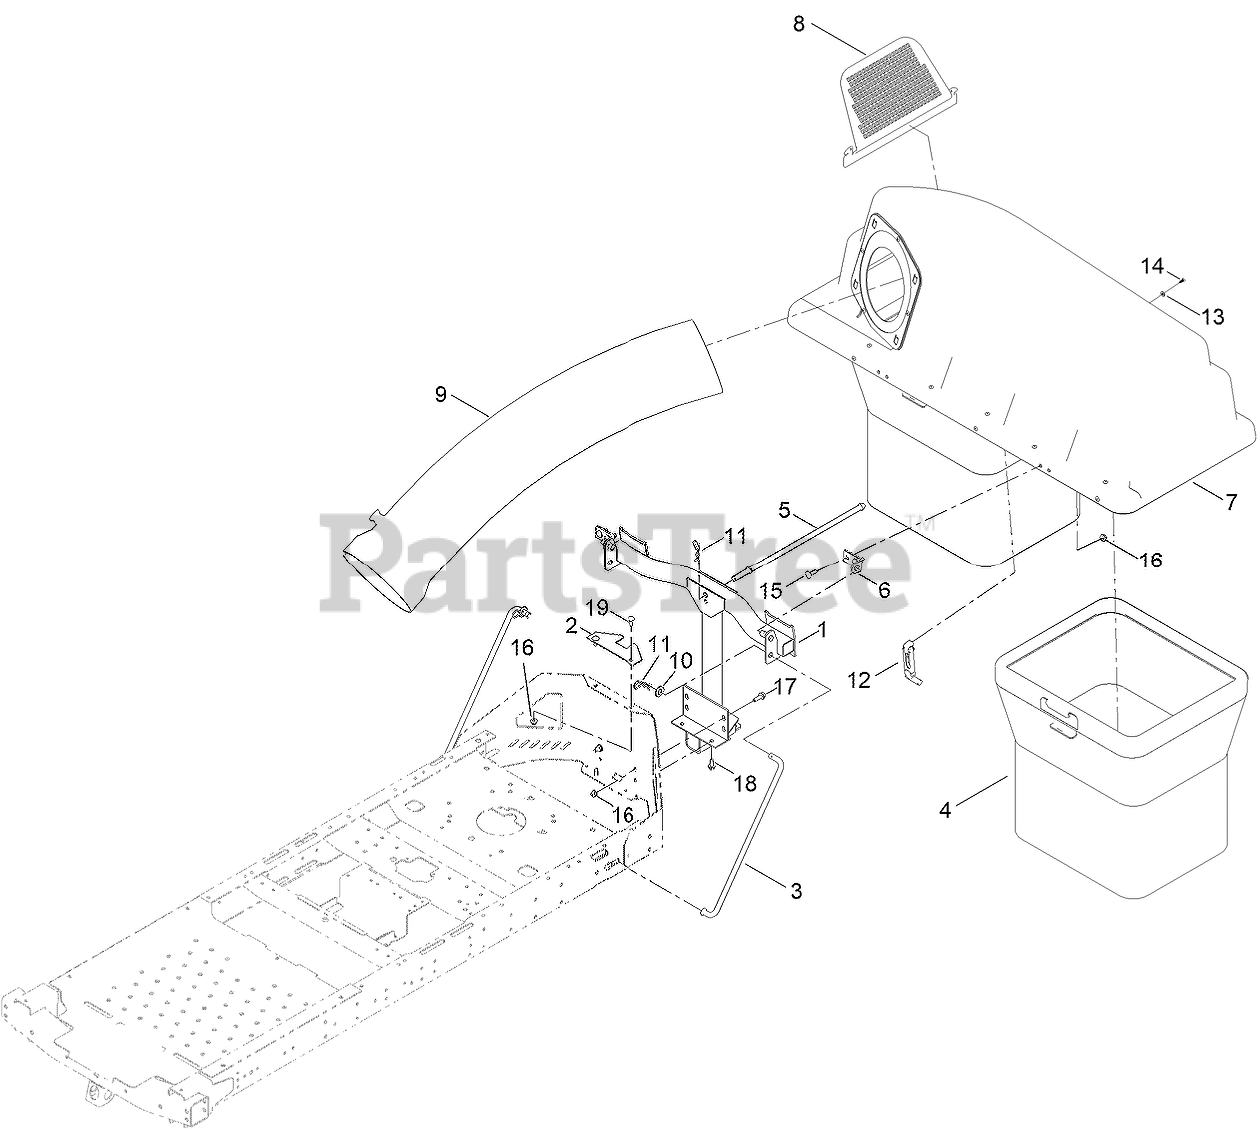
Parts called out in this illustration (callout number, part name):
1	Frame ASM, Pivot [black]
2	BRACKET-STABILIZER
3	ROD-SUPPORT, CZ
4	Bag ASM
5	ROD-HOOD, DOWN (HOLD)
6	BRACKET-HOPPER PIVOT
7	Top ASM-Bagger
8	SCREEN-BAGGER
9	TUBE-BAGGER
10	WASHER-FLAT
11	PIN-HAIR
12	LATCH-RUBBER
13	Washer-Plain
14	SCREW-PLASTIC, PTH
15	Bolt-CARR
17	SCREW-HHF
18	Screw-HWH 5/16-18 X 3/4 Tf
19	BOLT-CARR
